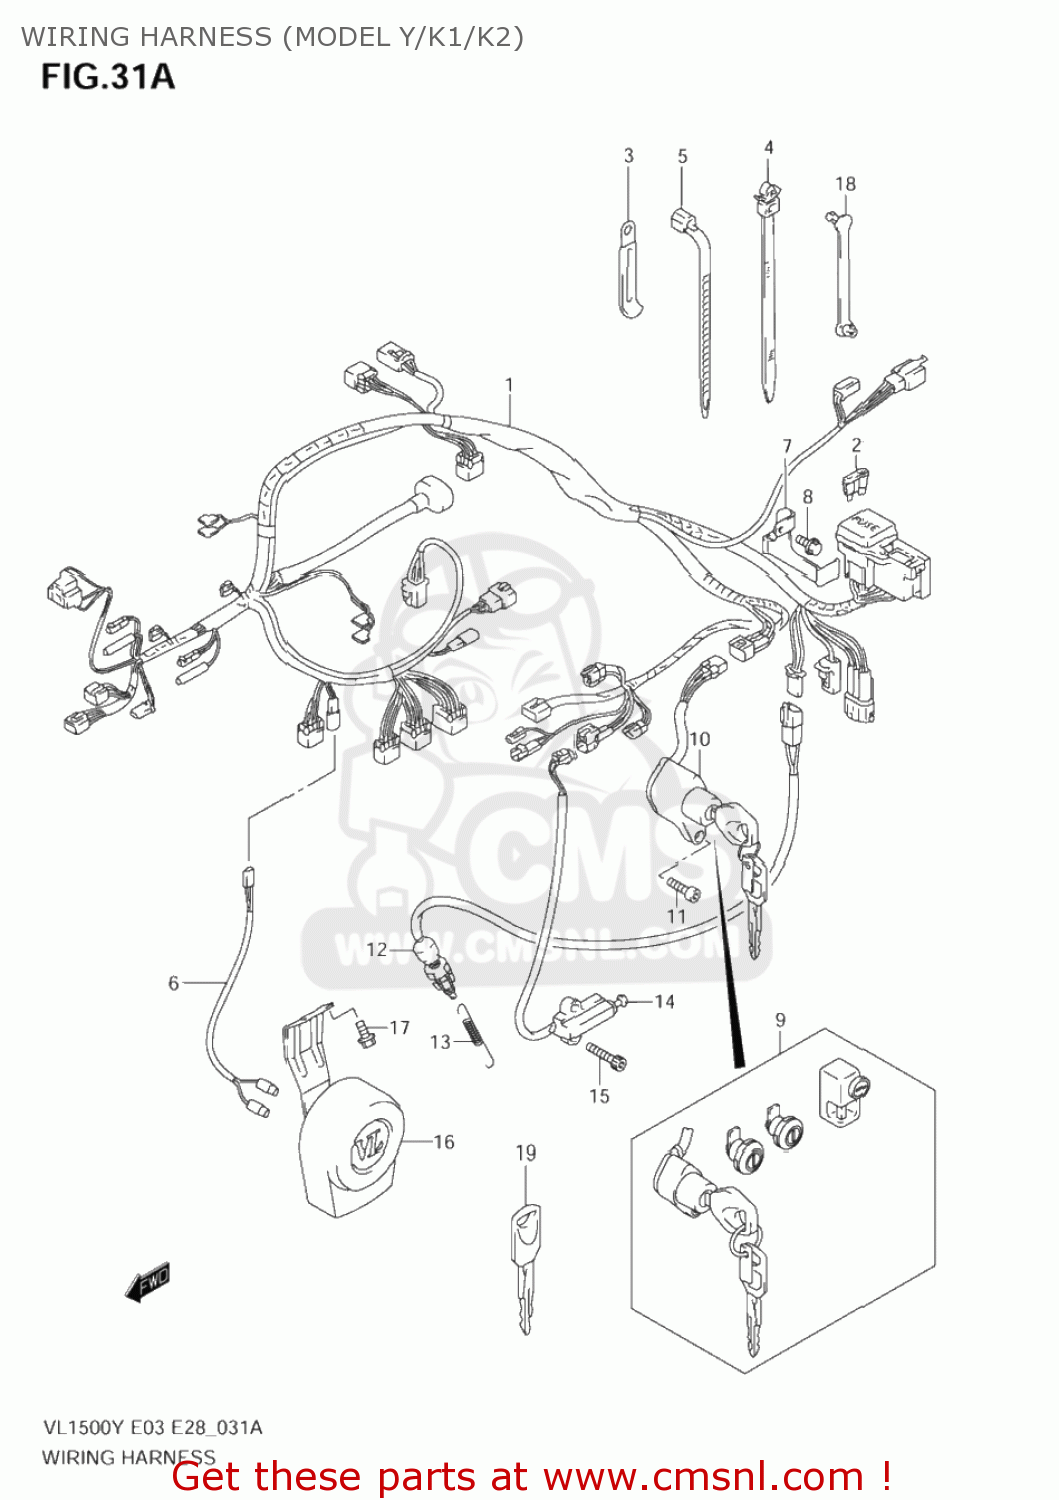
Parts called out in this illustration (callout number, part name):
1	HARNESS,WIRING
2	FUSE(10A)
3	CLAMP(L:65)
4	CLAMP(L:90)
5	CLAMP(L:125)
6	WIRE,HORN LEAD
7	BRACKET,FUSE
8	BOLT
9	LOCK SET
10	SWITCH ASSY,IG
11	BOLT,OIL FILLE
12	SWITCH ASSY,STOP LAMP
13	SPRING,STOP LAMP SWITCH
14	SWITCH ASSY,SIDE STAND
15	SCREW
16	HORN ASSY
17	BOLT
18	CLAMP(L:33)
19	KEY,BLANK
